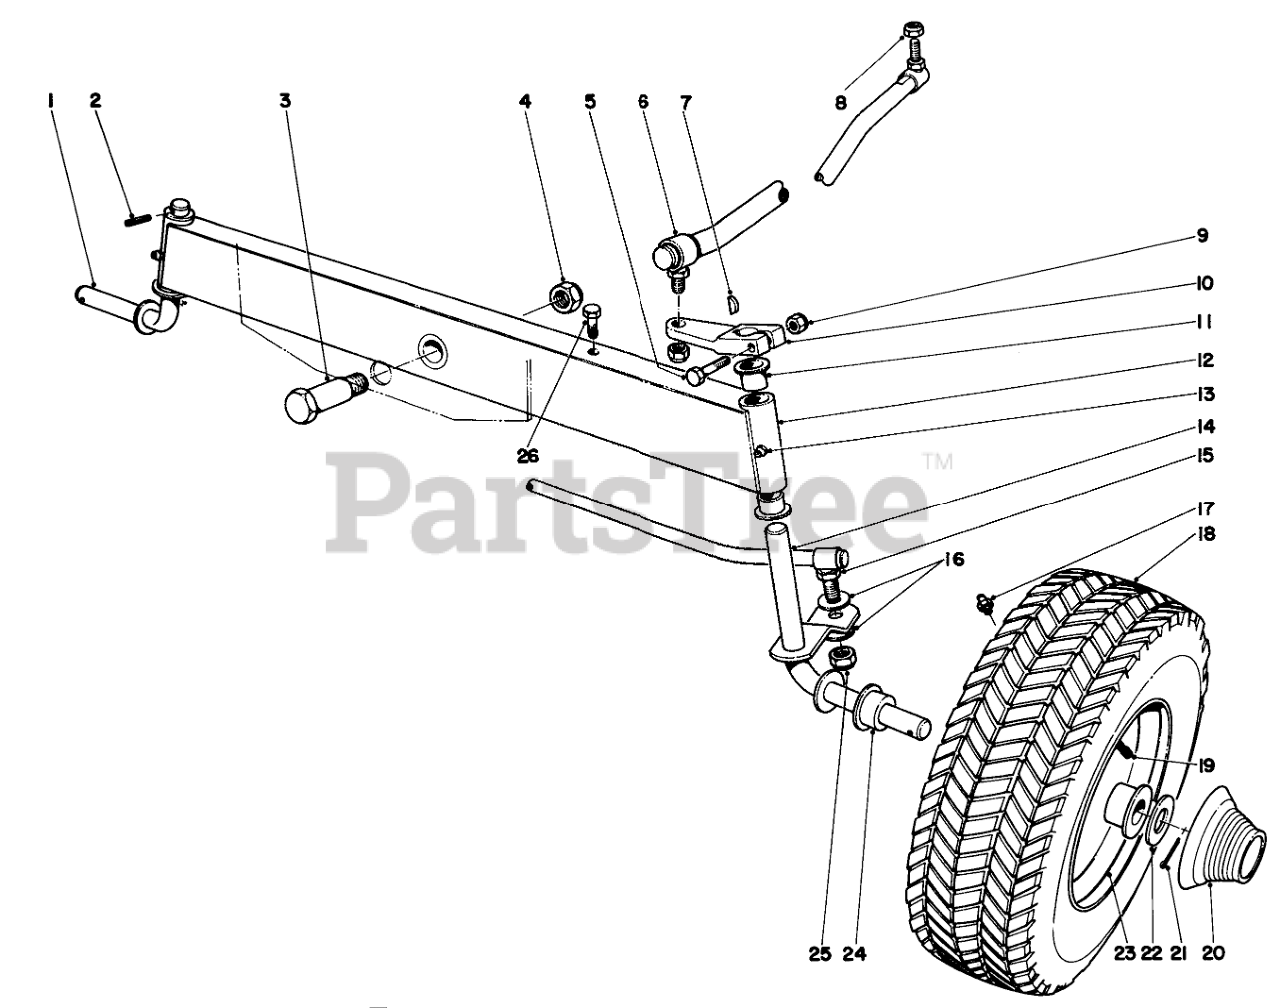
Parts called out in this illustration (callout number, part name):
2	PIN-SPRING
5	SCREW-HH
7	KEY-WOODRUFF
9	NUT-LOCK, CONE
10	Arm Drag Link
11	3/4IDX1LG FLANGE BSHG
12	Front Axle (Incl. Ref. #11)
13	GREASE FITTING
14	Spindle
16	WASHER-FLAT
17	FITTING-GREASE
21	PIN-COTTER
26	SCREW-HH, TAP
